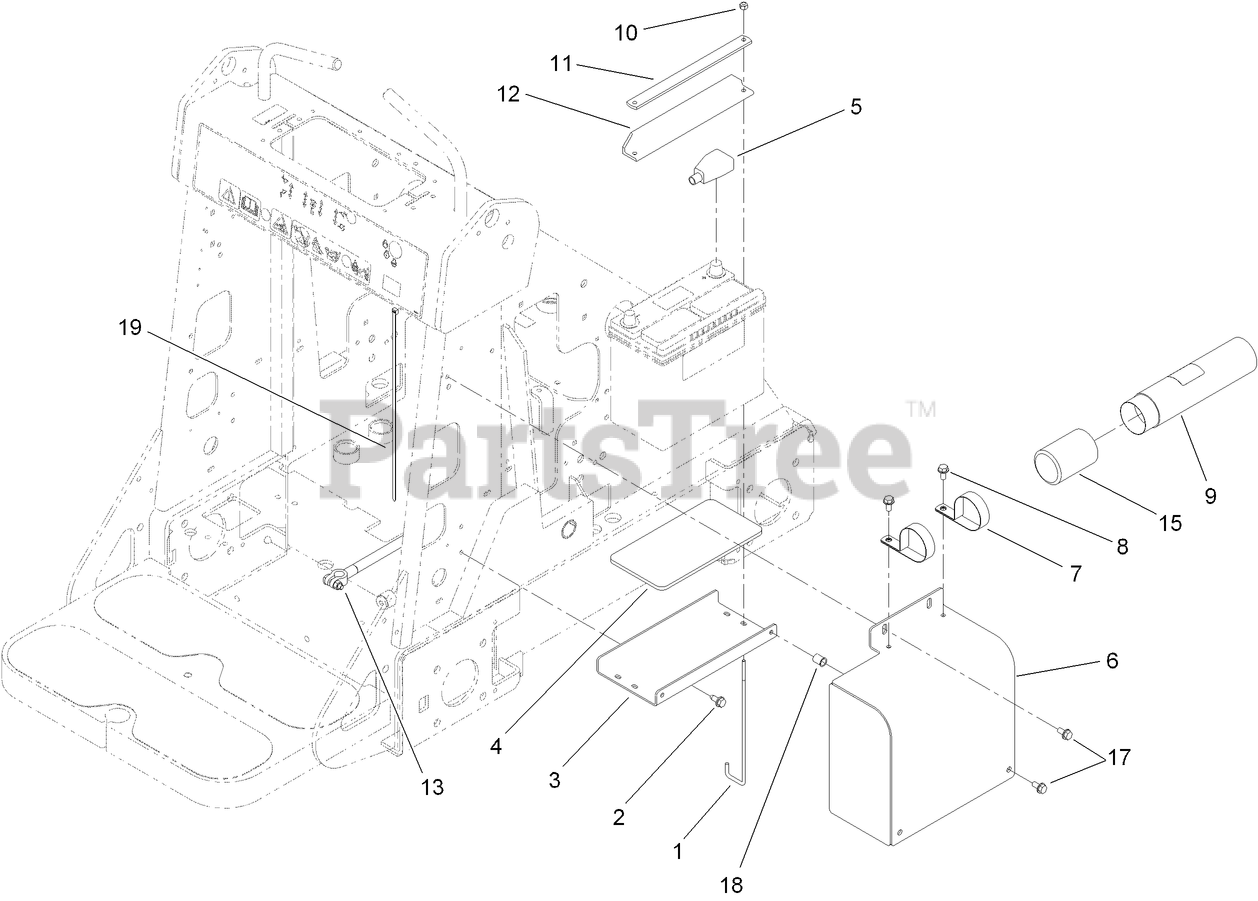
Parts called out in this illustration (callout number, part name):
1	RETAINER-BATTERY
2	SCREW-HWHTF
3	Mount-Battery
4	PAD-BATTERY
5	CABLE-BATTERY, POSITIVE
6	Cover-Battery
7	CLAMP-R
8	SCREW-HWHTF
9	TUBE-MANUAL
10	NUT-LOCK, NI
11	RETAINER-BATTERY
12	RETAINER-BATTERY
13	CABLE-BATTERY, NEGATIVE
15	CAP-HOUSING
17	SCREW-HHF
18	NUT-INSERT
19	TIE-CABLE
